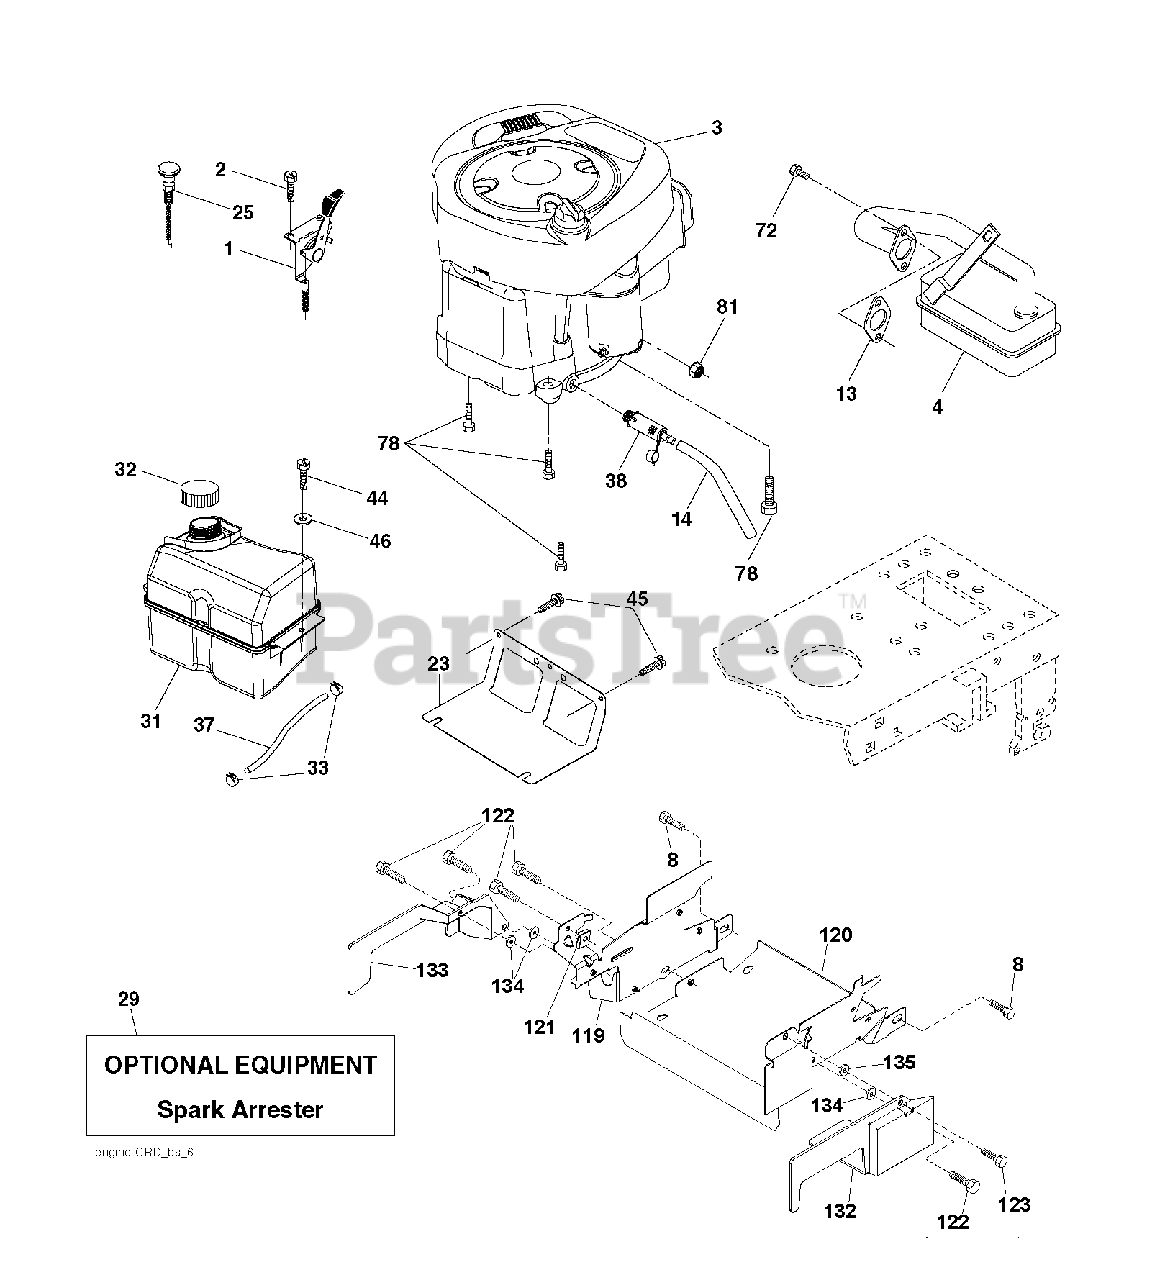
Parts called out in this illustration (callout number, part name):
1	CONTROL TH/CH FLAG
2	SCREW
8	BOLT, 5/16-18 X 1 3/4
13	REPL BY 532 27 22-93
14	TUBE, DRAIN OIL ASM.
23	SHEILD.BROWNING.DBR.GUARD
29	ARRESTER SPARK (OPTIONAL)
32	FUEL CAP
33	HOSE CLAMP
37	LINE.FUEL.20
38	PLUG DRAIN OIL EASY
44	SCREW HEXWSHR 1/4-20X3/4
45	SCREW, 3/8-16X3/4
72	SCREW.SOCKET HD.5/16-1
78	SCREW.3/8-16
81	NUT
122	SCREW.1/4-20X5/8
123	SCREW, 5/16-18 X 1/2
134	PALNUT 1/4
